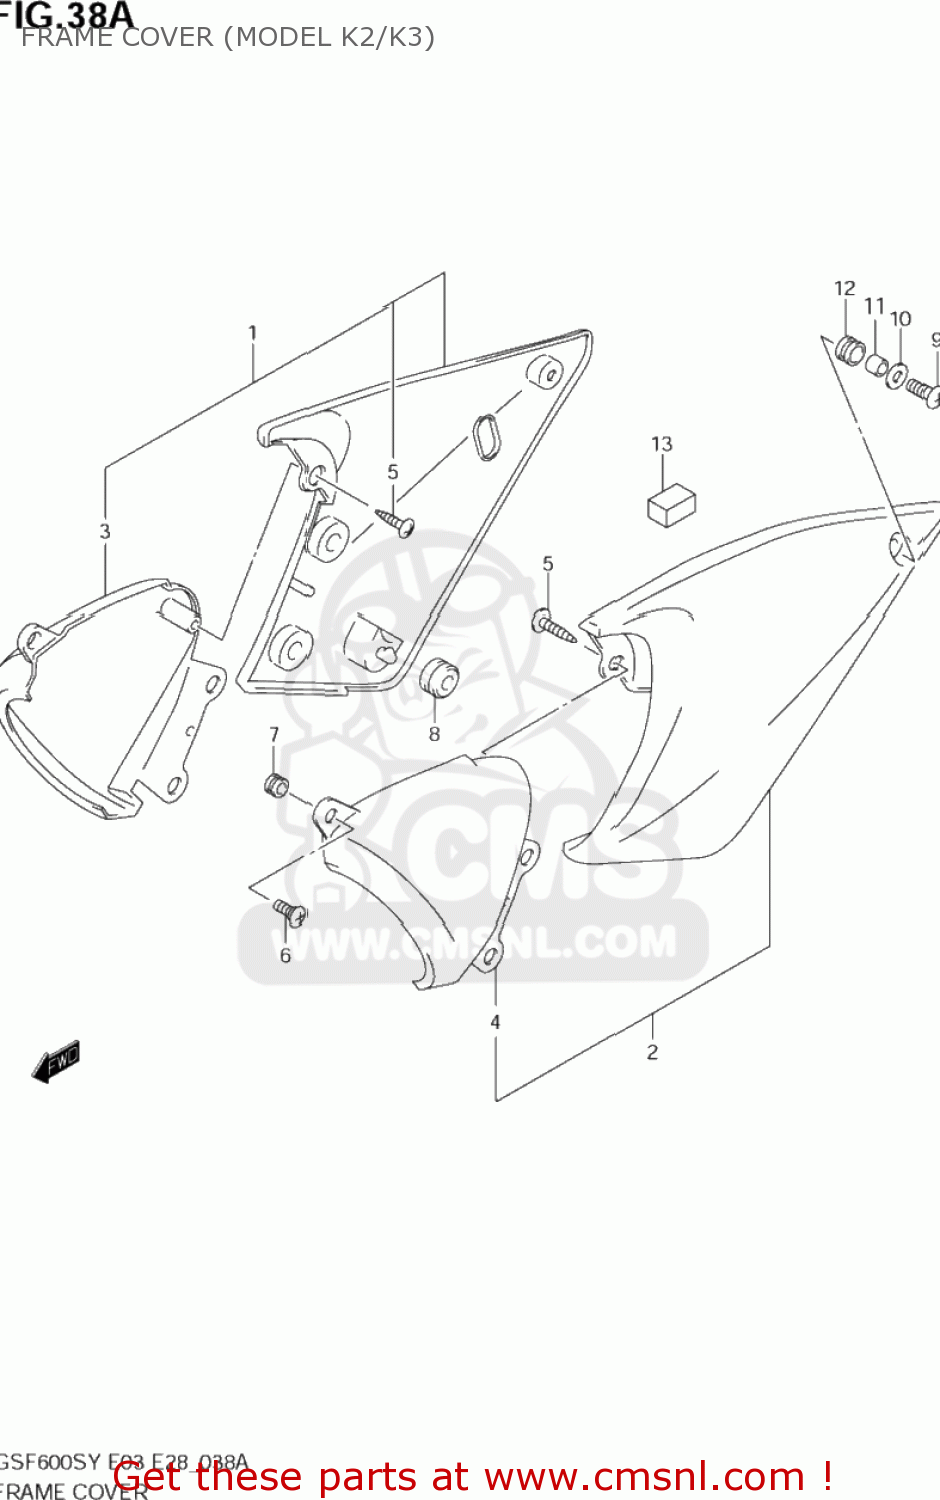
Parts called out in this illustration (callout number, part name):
1	COVER,FRAME,R(BLACK)
2	COVER,FRAME,L(BLACK)
3	COVER,FRAME FR,R
4	COVER,FRAME FR,L
5	SCREW
6	SCREW(5X16)
7	CUSHION,FRAME COVER FR
8	CUSHION
9	SCREW(6X16)
10	WASHER(6.5X18X1)
11	SPACER(6.5X9X9)
12	CUSHION
13	PAD,HEAD COVER CAP
